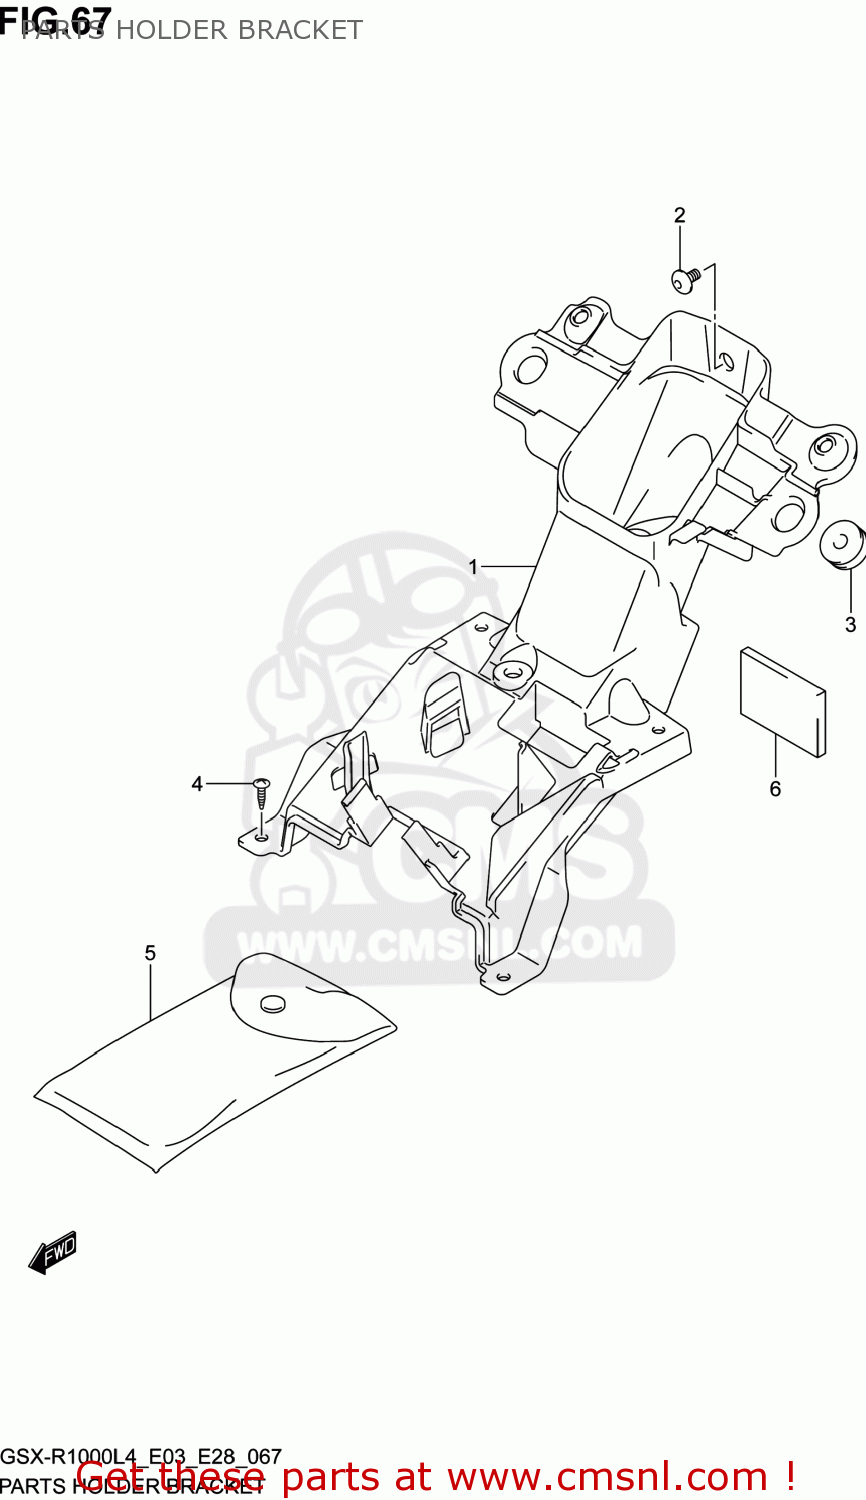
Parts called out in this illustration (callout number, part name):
1	BRACKET,ELECTRIC PARTS HOLDER
2	SCREW(6X12)
3	CUSHION
4	SCREW
5	TOOL ASSY
6	PROTECTOR(50X50X5)
